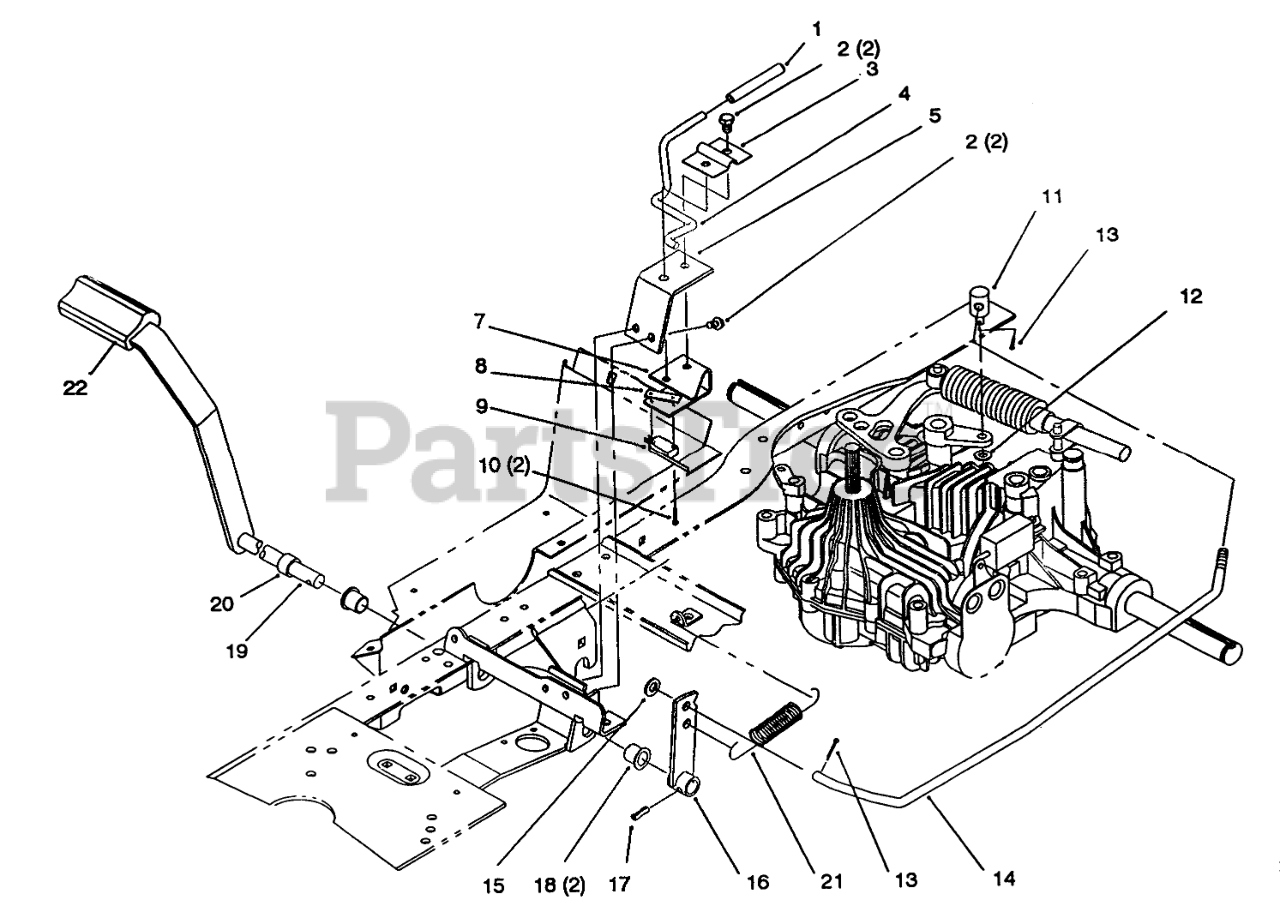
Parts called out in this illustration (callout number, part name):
1	Grip-Parking Brake (Only On: 72043, 72103, 72063, 72083)
2	Screw-HH (Only On: 72043, 72103, 72063, 72083)
3	Bracket-Park Brake (Only On: 72043, 72103, 72063, 72083)
4	Rod-Park Brake (Only On: 72043, 72103, 72063, 72083)
5	Support-Park Brake (Only On: 72043, 72103, 72063, 72083)
7	Bracket-Brake (Only On: 72043, 72103, 72063, 72083)
8	Nut-Speed (Only On: 72043, 72103, 72063, 72083)
9	Switch-Micro (Only On: 72043, 72103, 72063, 72083)
10	Screw (Only On: 72043, 72103, 72063, 72083)
11	Trunnion-Brake (Only On: 72043, 72103, 72063, 72083)
12	Washer-Flat (Only On: 72103, 72063, 72083, 72043)
13	Pin-Cotter (Only On: 72043, 72103, 72063, 72083)
14	Rod-Brake (Only On: 72043, 72103, 72063, 72083)
15	Washer-Flat (Only On: 72043, 72103, 72063, 72083)
16	Lever-Brake (Only On: 72043, 72103, 72063, 72083)
17	Pin-Spring (Only On: 72043, 72103, 72063, 72083)
18	Bushing-Flange (Only On: 72043, 72103, 72063, 72083)
19	Pedal-Brake (Only On: 72043, 72103, 72063, 72083)
20	Spacer-Brake (Only On: 72043, 72103, 72063, 72083)
21	Spring-Extension (Only On: 72043, 72103, 72063, 72083)
22	Pad-Pedal (Only On: 72043,72103, 72063, 72083)
